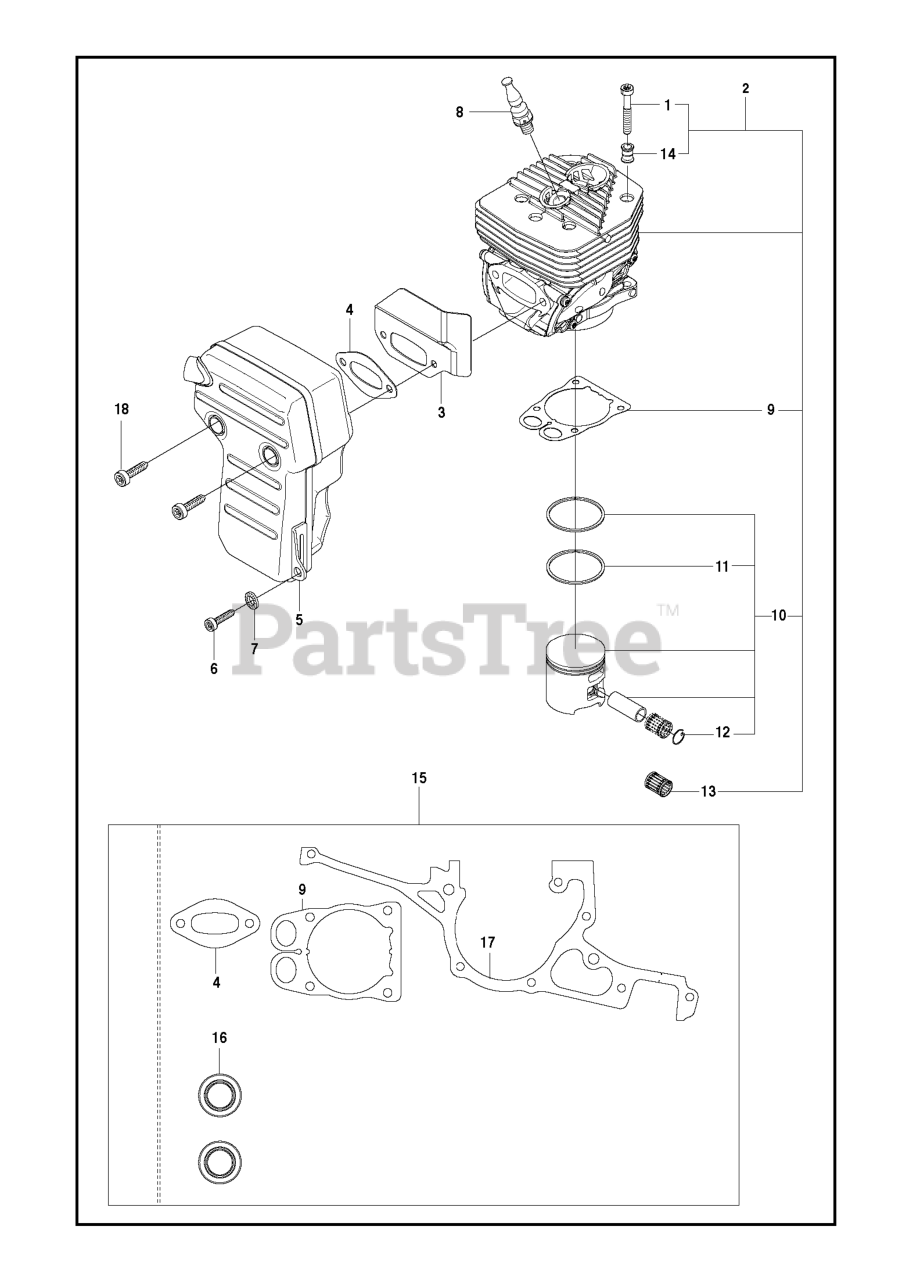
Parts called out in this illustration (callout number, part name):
1	SCREW ITXSCM M6X40/25 T27 12.
2	CYLINDER ASSY W PISTON SPARE P
3	HEAT DEFLECTOR
5	MUFFLER ASSY
7	DOUBLE WASHER
8	DECOMPRESSION VALVE K970II TOP
9	GASKET CYLINDER
10	PISTON
11	PISTON RING
13	SUPPORT BUSHING
14	SLEEVE CYLINDER
15	GASKET KIT K960 K970/K970-II/K
16	SEALING RING
17	GASKET CRANKCASE K970
